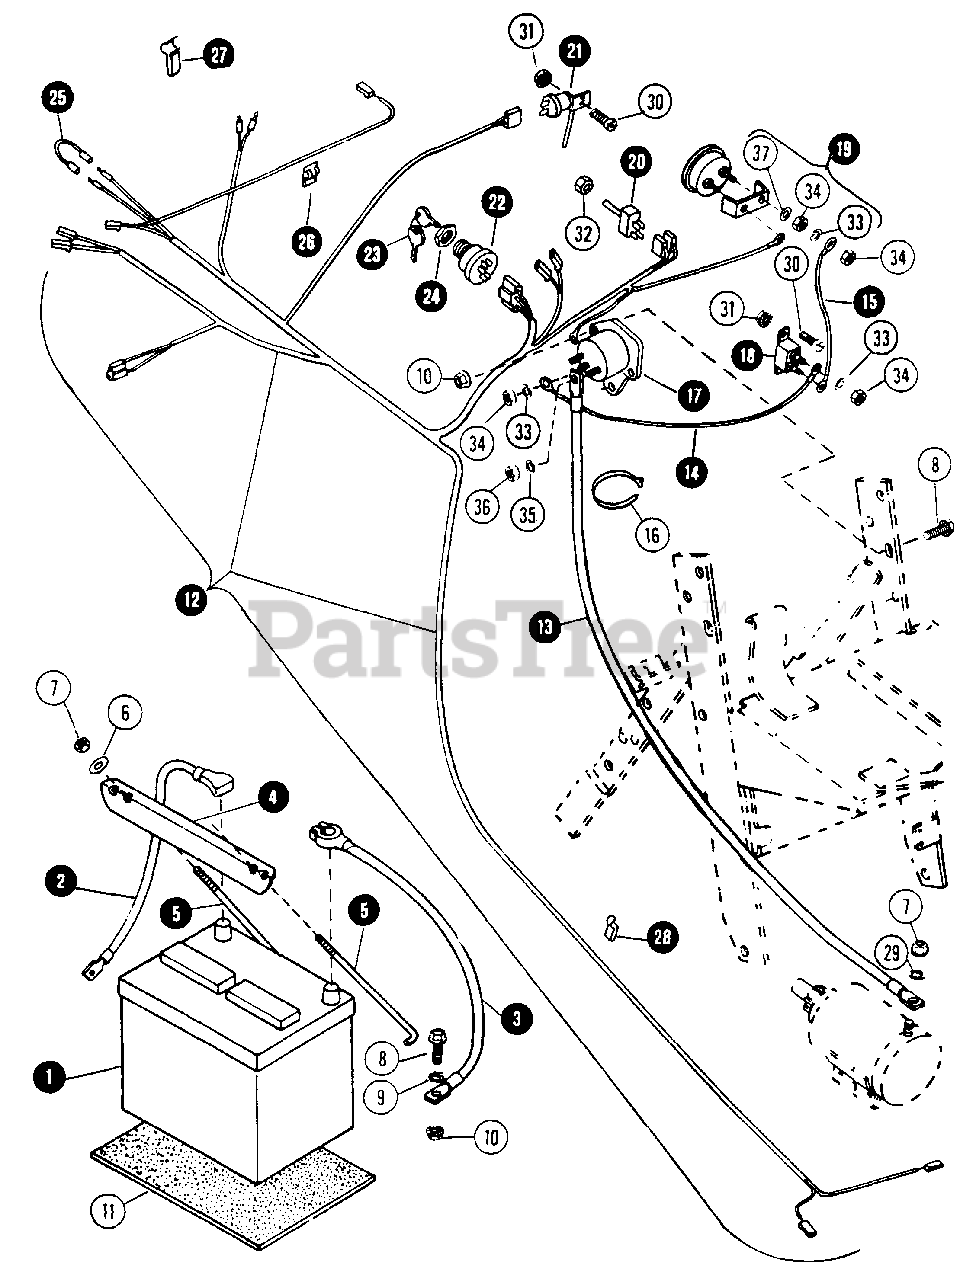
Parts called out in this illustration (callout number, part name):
1	BATTERY, 12 VOLT
2	CABLE ASSEMBLY, BATTERY TO SOLENOID (POSITIVE)
3	CABLE, BATTERY GROUND (NEGATIVE)
4	CLAMP, BATTERY HOLD DOWN
5	ROD, BATTERY HOLD DOWN
6	WASHER, 1/4 FLAT
7	NUT, 1/4C HEX LOCK
8	BOLT, 1/4C x 5/8 HEX FLANGE LOCK
9	WASHER, 1/4 EXTERNAL TOOTH LOCK
10	NUT, 1/4C HEX FLANGE LOCK
11	PAD, BATTERY
12	HARNESS, MAIN WIRING
13	CABLE, SOLENOID TO STARTER
14	WIRE ASSEMBLY, SOLENOID TO CIRCUIT BREAKER
15	WIRE ASSEMBLY, CIRCUIT BREAKER TO AMMETER
16	STRAP, WIRE RETAINING
17	SOLENOID, STARTING
18	BREAKER, CIRCUIT
19	AMMETER ASSEMBLY
20	SWITCH, TOGGLE (PTO LIFT)
21	SWITCH, INTERLOCK
22	SWITCH, IGNITION
23	KEY, IGNITION SWITCH (PAIR)
24	NUT, IGN. SWITCH MOUNTING
25	WIRE ASSEMBLY, PTO
26	CLIP, REAR FRAME
27	CLIP, REAR HARNESS
28	CLIP, FRONT HARNESS
29	WASHER, 1/4
30	SCREW, #10-24 x 1/2 ROUND HEAD
31	NUT, #10-24 HEX FLANGE LOCK
32	NUT, 1/2-27 HEX (SPECIAL)
33	WASHER, #10 LOCK
34	NUT, #10-32 HEX
35	WASHER, 5/16 LOCK
36	NUT, 5/16C HEX
37	WASHER, #10 FLAT
